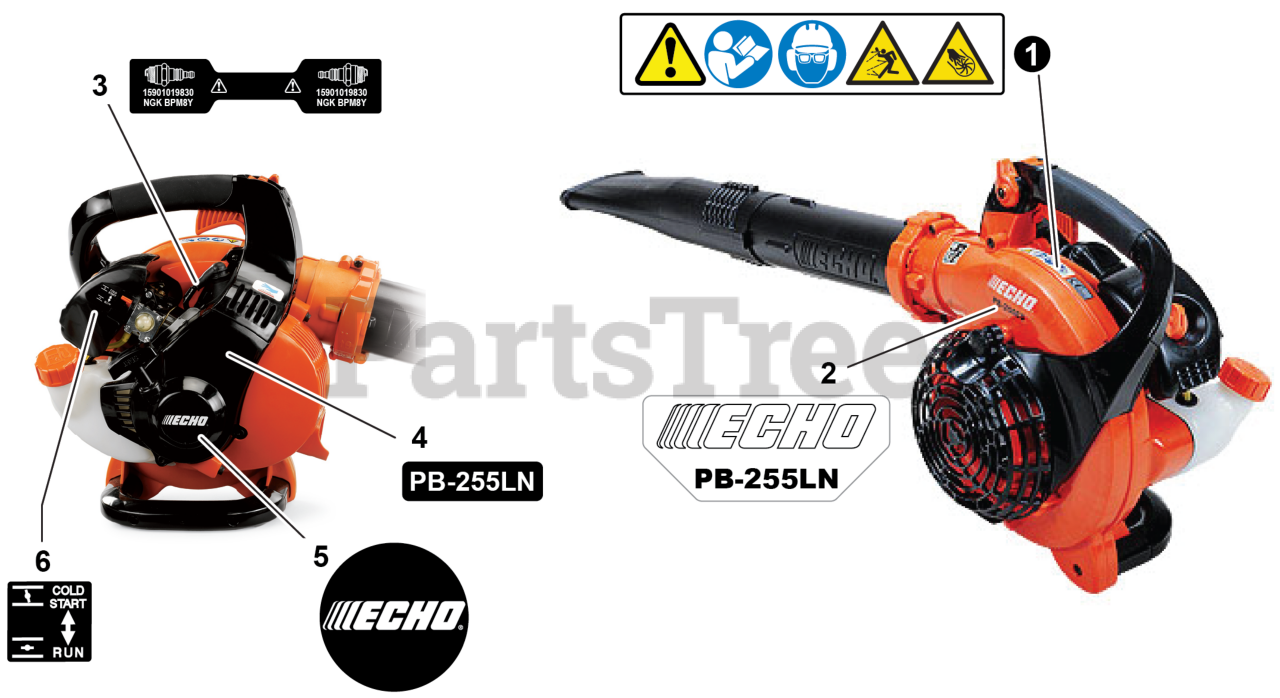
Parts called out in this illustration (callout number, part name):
1	LABEL - CAUTION - ISO
2	LABEL - PB-255LN
3	LABEL - SPARK PLUG - BPM8Y
4	LABEL - MODEL PB-255LN
5	LABEL - STARTER - ECHO
6	LABEL - CHOKE
